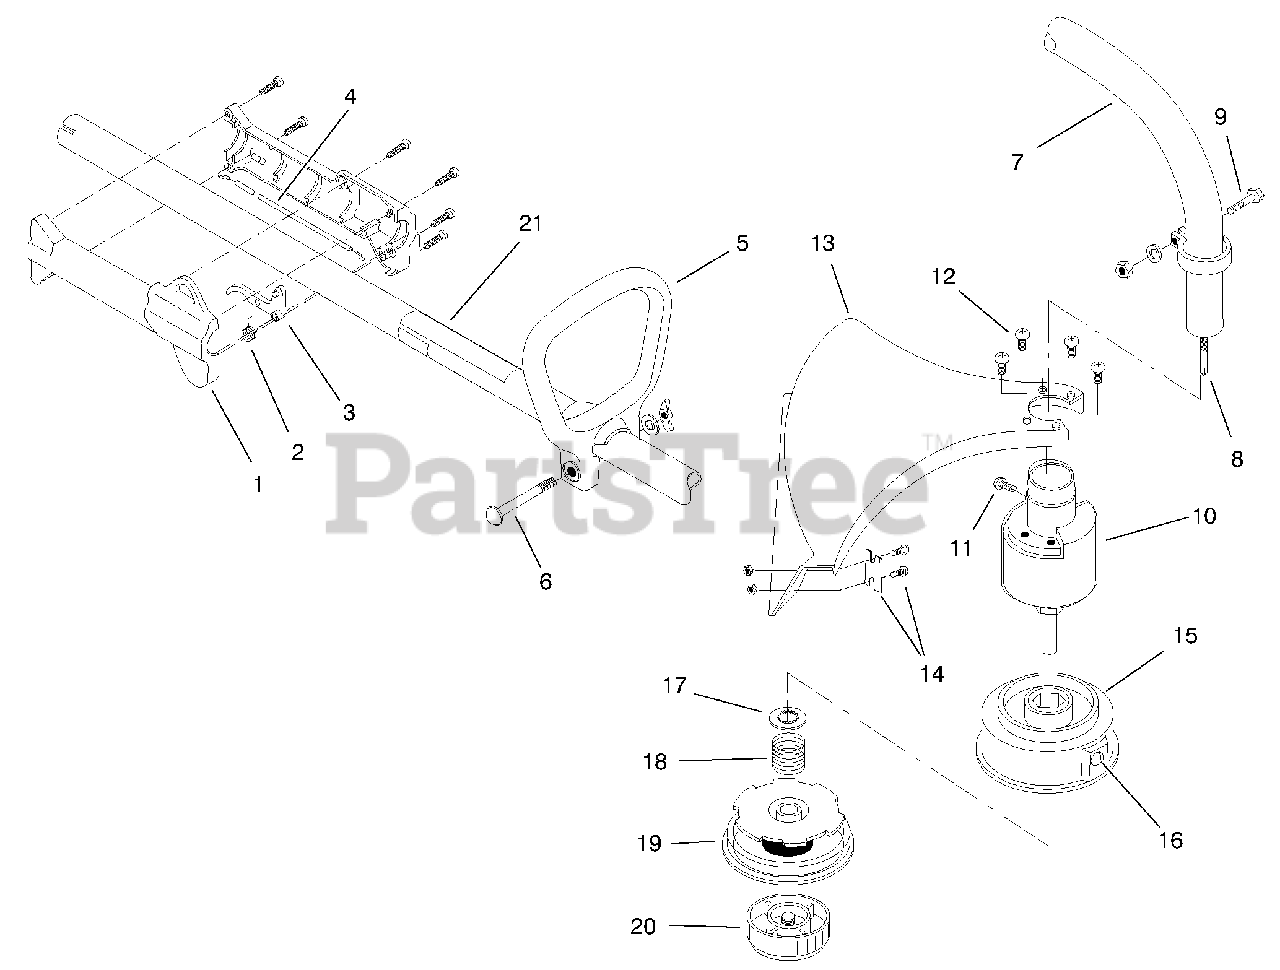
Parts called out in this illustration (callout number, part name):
1	Throttle Housing & Trigger ASM
3	Throttle Trigger
4	Throttle Cable ASM
5	D-Handle
6	D-Handle Hardware ASM
7	Drive Shaft Housing ASM
8	Drive Shaft
9	Lower Clamp ASM
10	Housing-Bushing ASM
11	Screw-Anti-Rotation
12	Screw-Shield Mounting
13	Shield & Blade ASM (Includes Ref #14)
14	Blade ASM
15	Outer Spool & Eyelet
17	Retainer
19	Inner Reel
20	Bump Knob ASM
21	Decal-Safety Symbols
